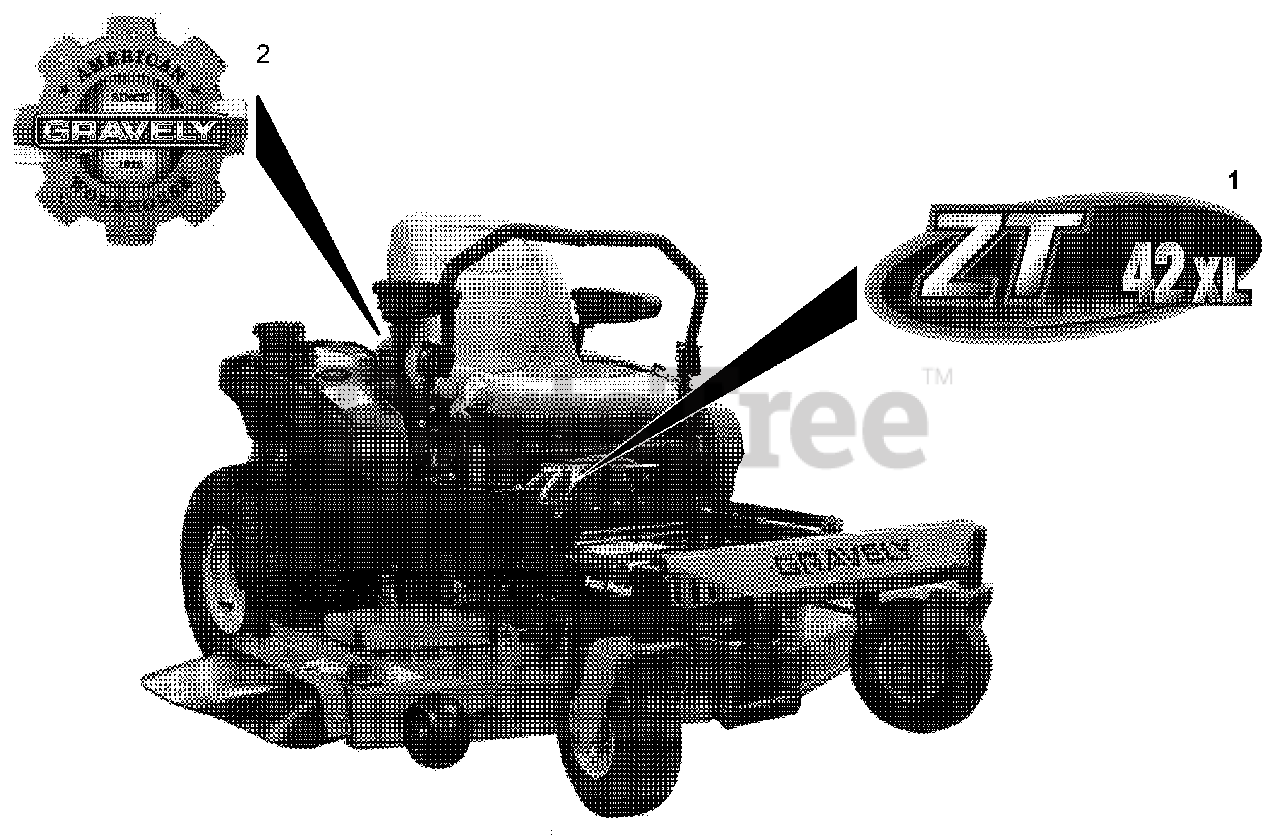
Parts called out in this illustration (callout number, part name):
1	Decal, 42 ZT XL
1	Decal, 48 ZT XL
1	Decal, 54 ZT XL
2	Decal, Gravely American Heritage
